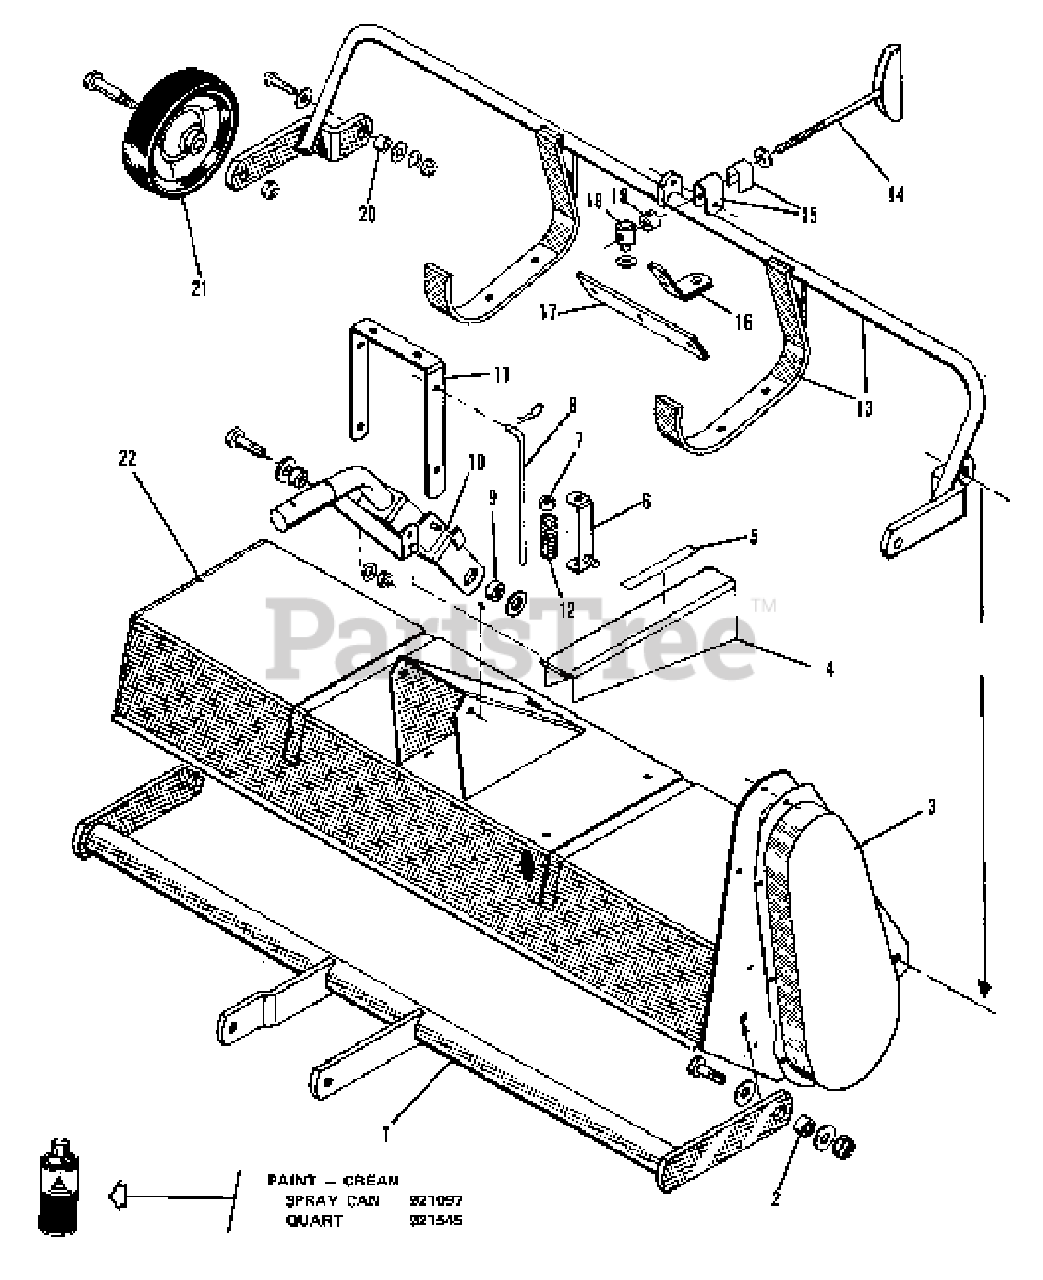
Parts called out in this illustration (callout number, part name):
1	HITCH ASSEMBLY, Thatcher
2	CAPSCREW, 1/2NC x 1-1/4
2	WASHER, 1/2 Plain
2	NUT, 1/2NC, Lock
3	GUARD, Chain
3	SCREW, 1/4NC x 3/8, Taptite
4	GUARD, Belt
4	BOLT, 5/16NC x 3/4
4	NUT, 5/16NC, Wing
5	DECAL, Safety
6	BRACKET ASSEMBLY, Rod Guide
6	NUT, 5/16NC, Lock
7	COLLAR, Set
7	SETSCREW, 1/4NC x 3/8, Square Head
8	ROD, Clutch
8	PIN, Quick
9	CAPSCREW, 7/16NC x 3-1/2
9	LOCKWASHER, 7/16
9	NUT, 7/16NC
9	WASHER, 3/8, Plain
9	WASHER, 7/16, Plain
9	CAPSCREW, 7/16NC x 1-1/4
10	BAR ASSEMBLY, Lift
10	PIN, Round Head Hitch
10	PIN, Quick
11	HANDLE, Clutch
11	PIN, Quick
13	BAR ASSEMBLY, Adjuster
14	SCREW ASSEMBLY, Hand Control
14	WASHER, 3/8, Plain
15	GUIDE, Rod
15	LINER, Rod Guide
15	CAPSCREW, 5/16NC x 1-1/4
15	NUT, 5/16NC, Lock
17	BAR, Reinforcement
17	BOLT, 5/16NC x 1
17	BOLT, 5/16NC x 3/4
17	LOCKWASHER, 5/16
17	NUT, 5/16NC
18	PIVOT, Control
18	WASHER, 5/16
18	PIN, Cotter, 3/32 X 3/4
19	COLLAR, Set
19	SETSCREW, 1/4NC x 5/16, Socket Head
20	CAPSCREW, 3/8NC x 1-1/4
20	WASHER, 3/8, Plain
20	LOCKWASHER, 3/8
20	NUT, 3/8NC
21	WHEEL ASSEMBLY, With Tire
21	BOLT, Wheel
21	NUT, 7/16NC, Lock
22	HOUSING ASSEMBLY, 38" Thatcher
22	PLUG, Button
